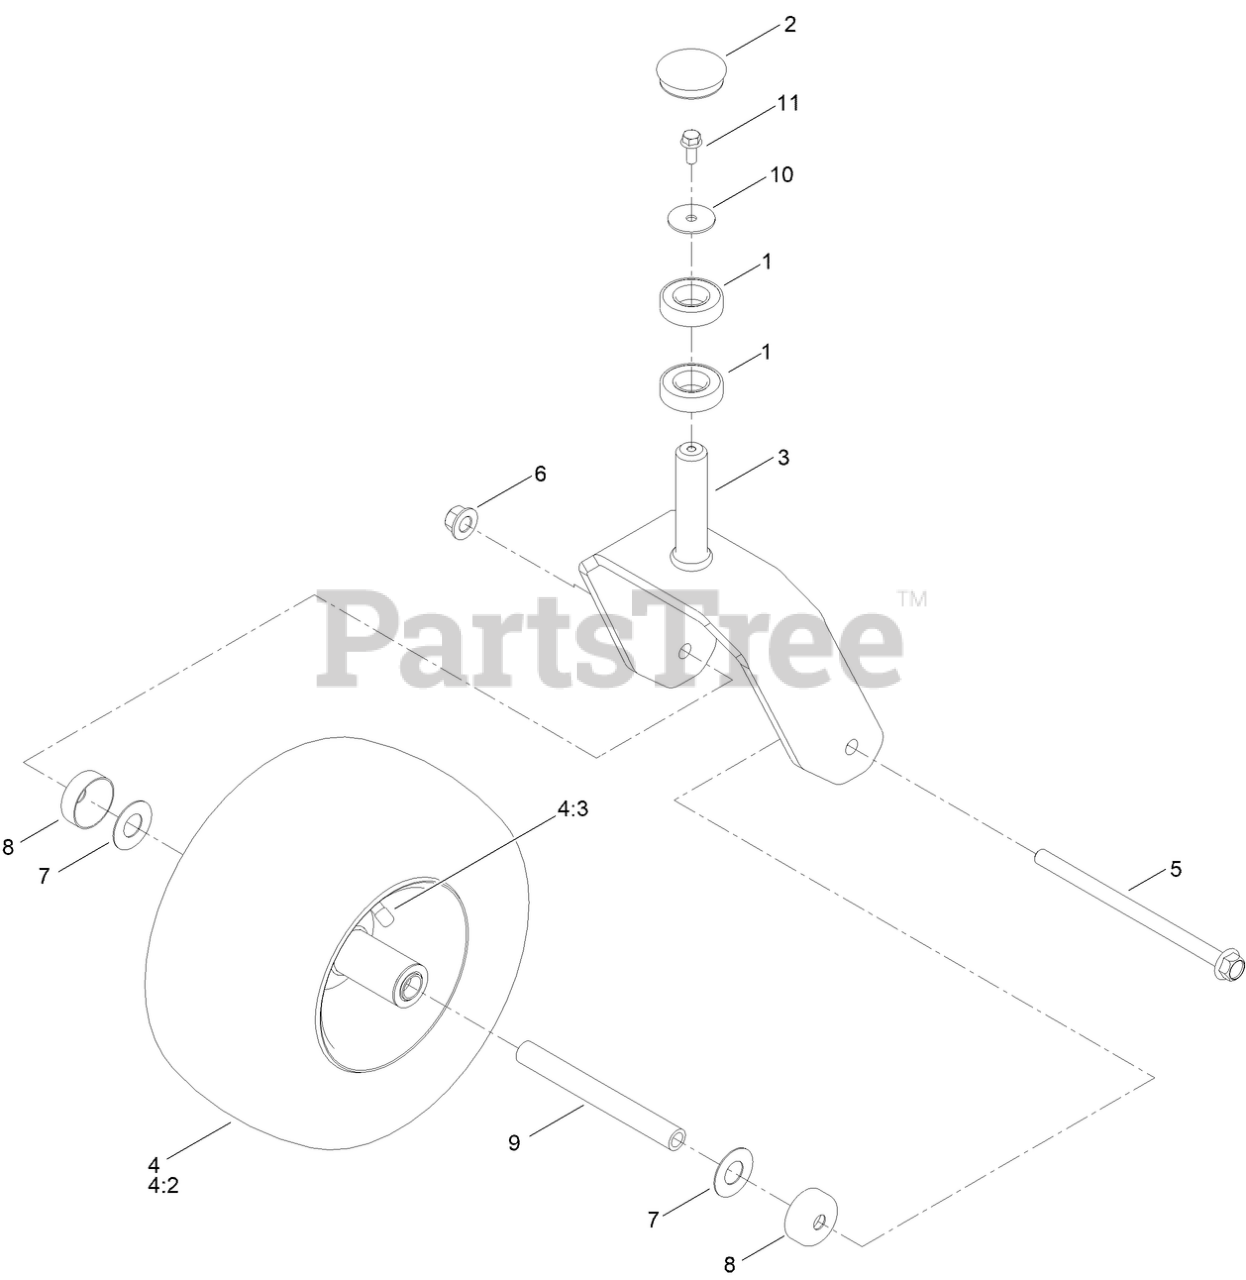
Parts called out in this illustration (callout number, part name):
1	BEARING-BALL
2	CAP,GREASE
3	FORK ASM [BLK-TXT]
4	CASTER TIRE ASM 13X6.5-6
4:2	TIRE 13X6.5-6
5	SCREW-HHF
6	NUT-LOCK
7	WASHER
8	GUARD-SEAL
9	SPANNER-WHEEL
10	WASHER-FLAT
11	SCREW-HHF
